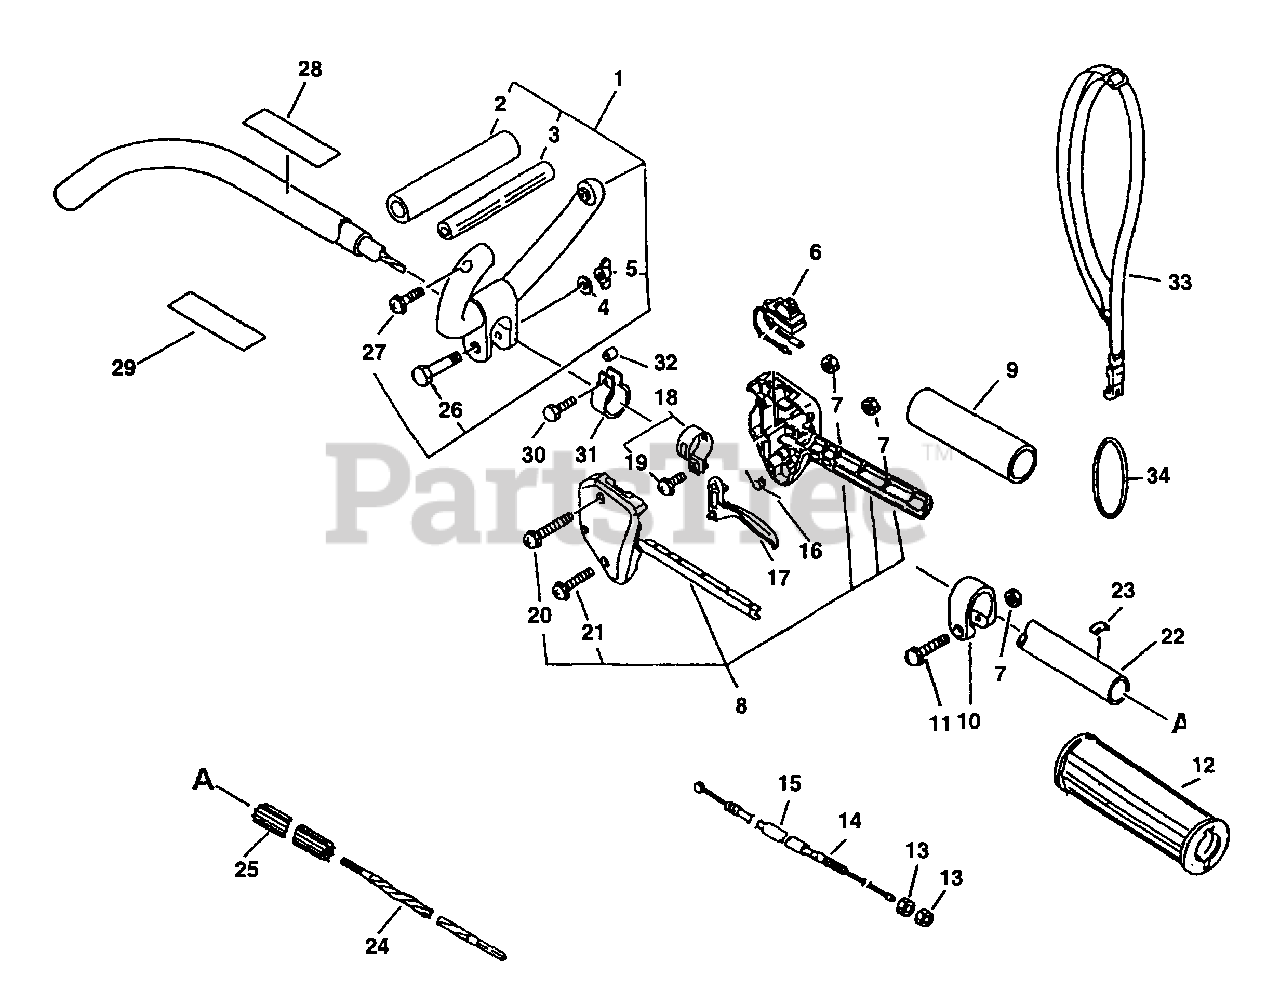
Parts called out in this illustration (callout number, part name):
1	LOOP HANDLE ASSY
2	GRIP, HANDLE
4	WASHER 6.5×11.5×0.8
5	NUT, WING 6
6	IGNITION SWITCH ASSY
7	NUT M5
8	THROTTLE BRACKET SET
9	GRIP, HANDLE
11	SCREW 5×28
14	CABLE, THROTTLE
16	SPRING, TORSION
17	TRIGGER, THROTTLE
18	CLAMP KIT
19	SCREW 5×14
20	SCREW 5×35
21	SCREW 5×25
22	MAIN PIPE ASSY
23	LABEL - ALIGNMENT
24	DRIVESHAFT - FLEXIBLE
25	LINER - FLEXIBLE
26	BOLT - 6×40
27	SCREW 5×30
28	LABEL, CAUTION
29	LABEL, CAUTION
30	BOLT 5×18
31	HOOK
32	SPACER, GUARD
33	SHOULDER STRAP ASSY
34	RING, HARNESS Ø32
